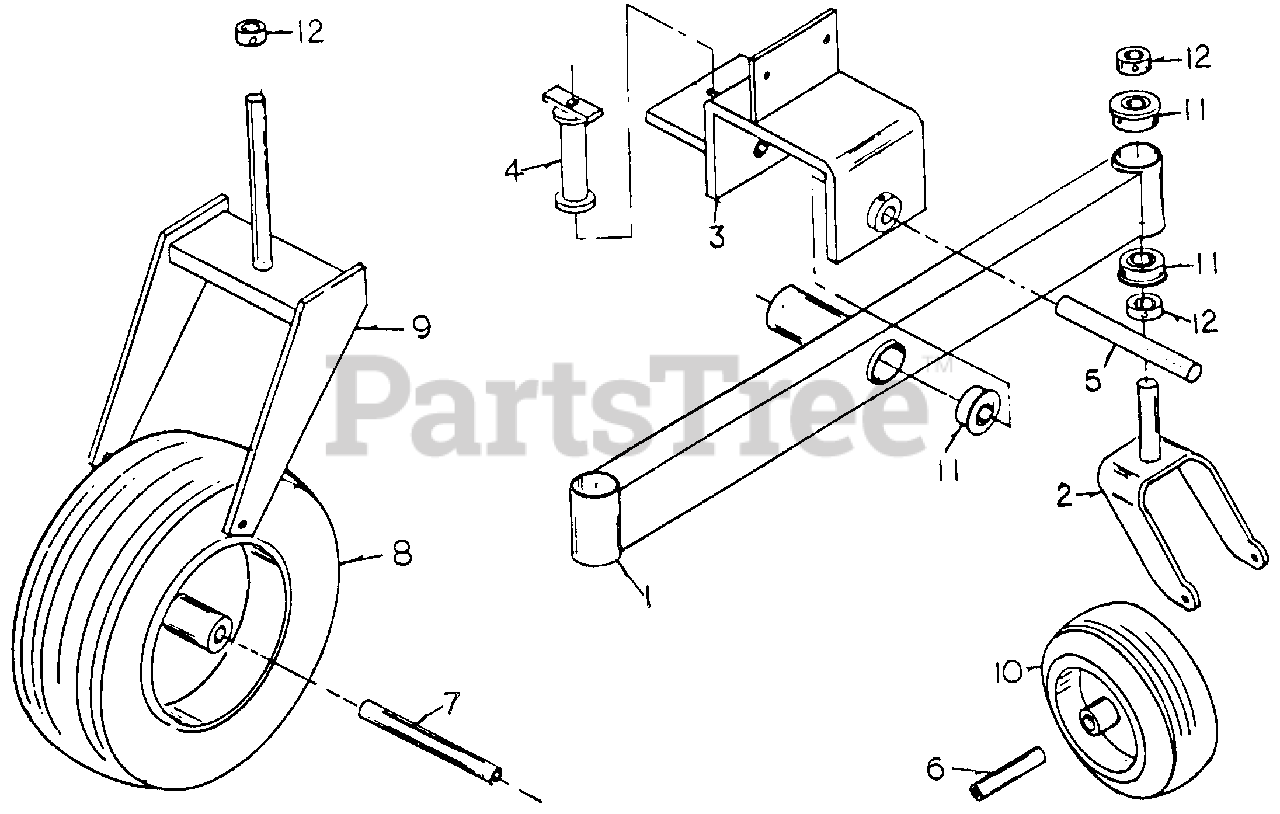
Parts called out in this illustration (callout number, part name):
1	Dual Tail Wheel Axle
2	Dual Tail Wheel Fork
3	Dual Tail Wheel Mount
4	Dual Tail Wheel Tube Block
6	Tail Wheel Axle
8	Tail Wheel Assembly
9	Tail Wheel Fork
10	Tail Wheel Assembly
12	Set Collar, 1"
